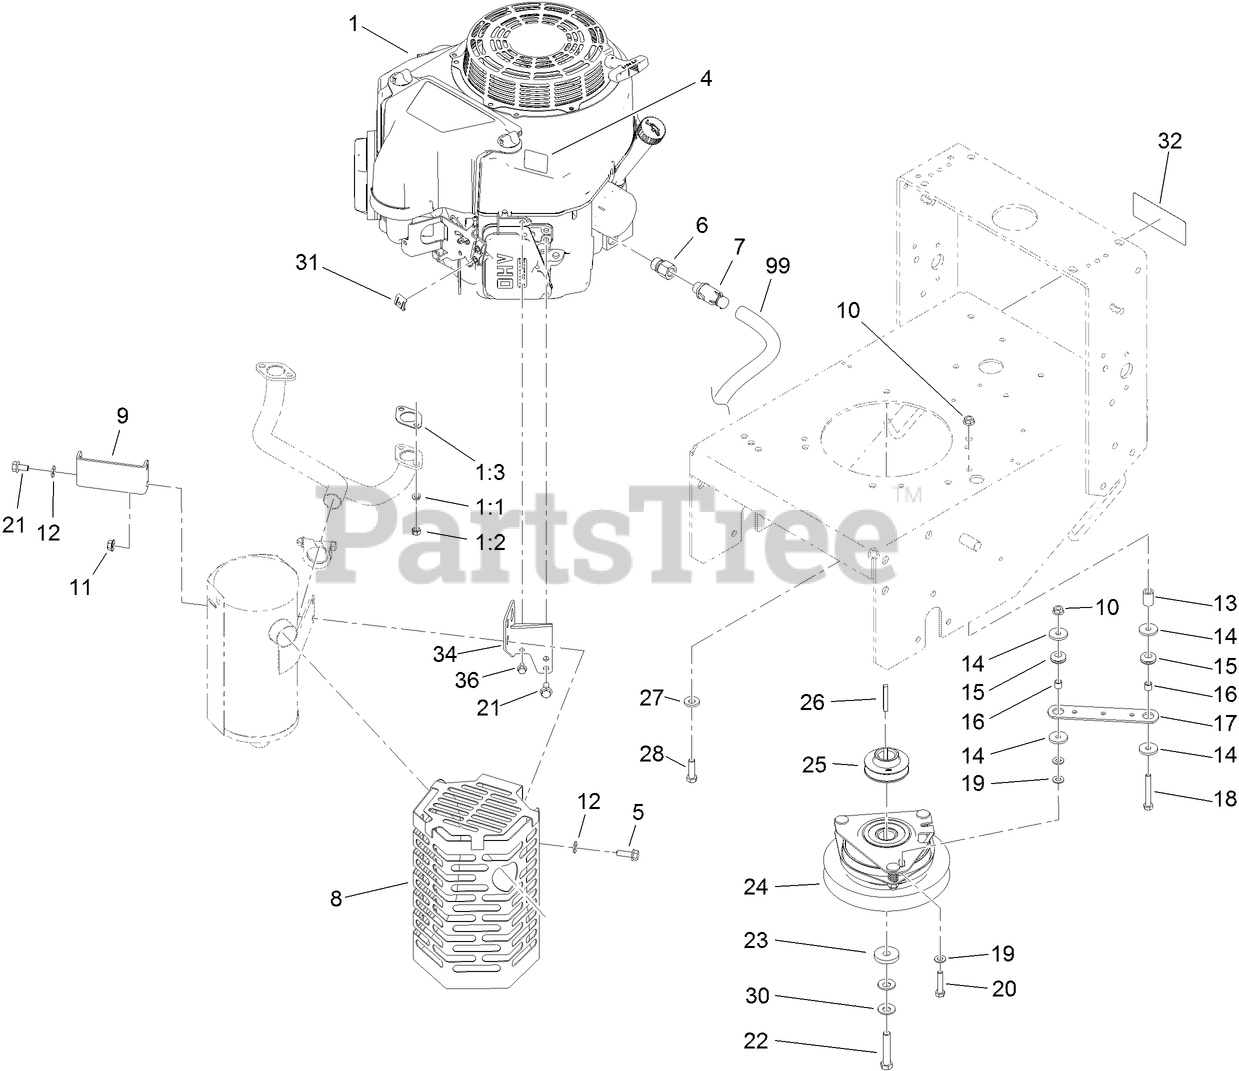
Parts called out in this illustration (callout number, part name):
1:1	WASHER-LOCK
1:3	GASKET-EXHAUST
4	DECAL-WARNING
5	SCREW-HHF
6	Adapter
7	VALVE-DRAIN, OIL
8	SHIELD-MUFFLER
9	BRACKET-SHIELD, MUFFLER
10	NUT-HF
11	NUT-HF, LOCK
12	WASHER-SPRING
13	TUBE-RETAINER
14	WASHER
15	GROMMET
16	SPACER
17	STRAP-CLUTCH, BRAKE
18	SCREW-HH
19	WASHER-PLAIN
20	SCREW-HH
21	SCREW-HHF
22	SCREW-HH
23	WASHER
24	CLUTCH / BRAKE ASM
25	PULLEY-DRIVE
26	KEY-SQUARE
27	WASHER-BELLEVILLE
28	SCREW-HH
30	WASHER-SPRING
31	CLAMP-CABLE
32	DECAL-CAUTION
34	BRACKET-MUFFLER
36	SCREW-HHF
99	HOSE-DRAIN, OIL
